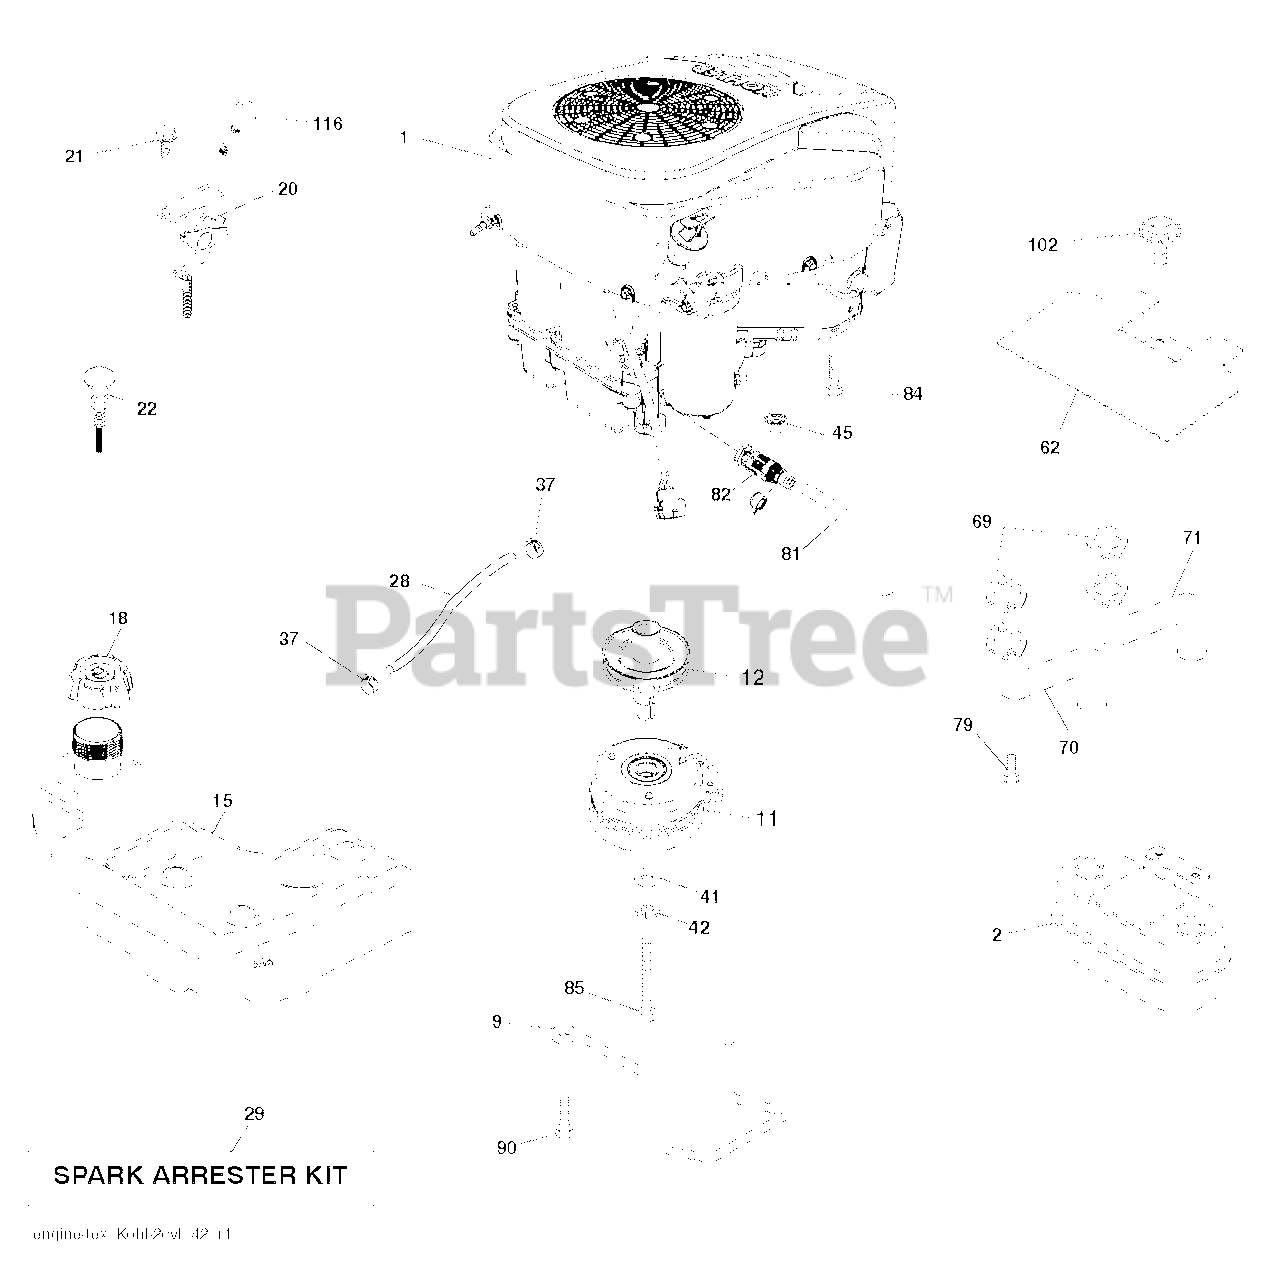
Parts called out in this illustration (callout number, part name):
2	MUFFLER.ASM.TWN.EXTNDED.DFLCTR
9	KEEPER.BELT.ENGINE.4.2
11	CLUTCH. 5.0 PD. 2.5 OFFSET
12	PULLEY.EXTENDED.SHAFT.GROUND
15	TANK.ASSY.3.GAL.EPA
18	CAP ASSY FUEL 3" GRAY
20	CONTROL.THROTTLE.PRO.
21	SCREW.#10 X 0.750.BOS
22	CONTROL.CHOKE.ERGO.PUSH-IN.BLA
28	LINE.FUEL.64"REAR.EMIS
29	KIT.SPARK ARRESTOR 794945 B&S
37	HOSE CLAMP
42	LOCKWASHER
45	NUT
62	SHIELD.HEAT.MUFFLER
70	TUBE.EXHAUST.LH.FR961/FR730
71	TUBE.EXHAUST.RH.FR961/FR730
79	SCREW.SOCKET HD.5/16-1
81	TUBE, DRAIN OIL ASM.
82	VALUE.OIL.DRAIN
84	SCREW 3/8-16X1
85	BOLT.HEX.7/16-20 X 5
90	SCREW 3/8-16X1
102	SCREW
116	KNOB - SHIFT
